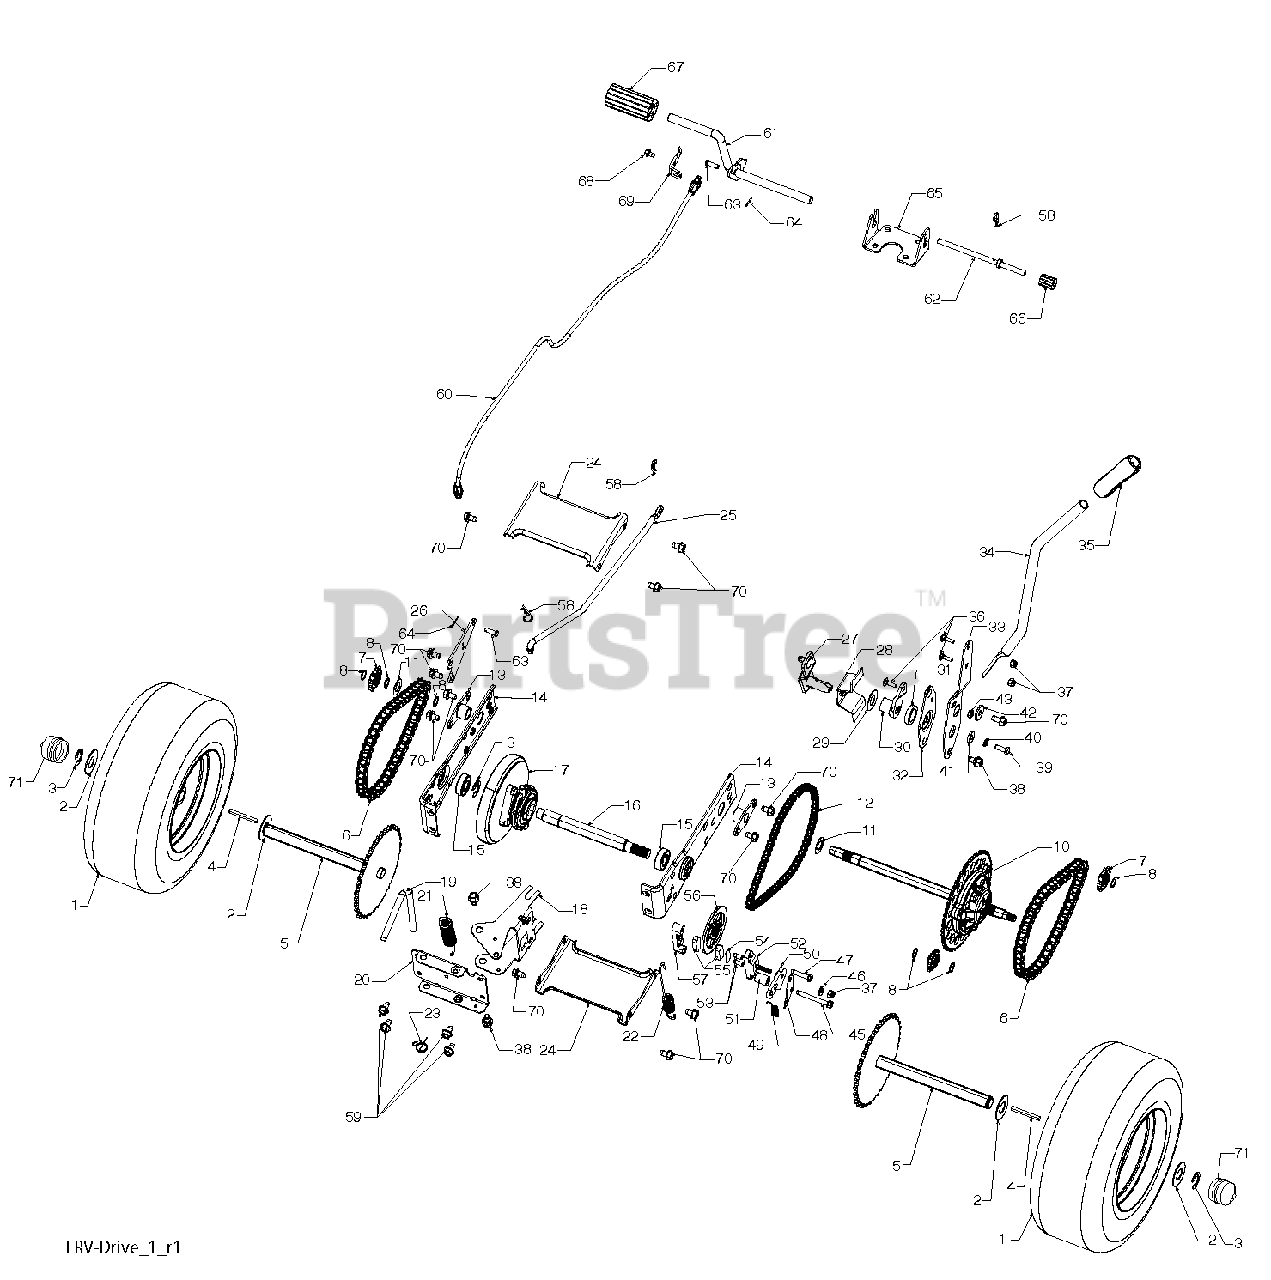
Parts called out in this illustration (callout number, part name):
1	WHEEL ASM (REAR)
2	WASHER, 16 GA.
3	E-CLIP
4	KEY. SQUARE
5	WELDMENT. DRIVE AXLE
6	CHAIN DRIVE
7	SPROCKET. 9 TOOTH SPLINED
8	RING, SNAP
10	DIFFERENTIAL ASM
11	WASHER, THRUST
12	CHAIN, PRIMARY DRIVE
13	BUSHING
14	BRACKET, CARRIER
15	BEARING ASM
16	SHAFT INPUT
17	WHEEL, FRICTION A5M
18	ARM, SHIFT
19	ROD, BYPASS
20	BRACE CARRIER REAR
21	SPRING, CARRIER
22	SPRING, BRAKE
23	SPRING, BYPASS
24	BRACE CARRIER BOX
25	LINK, SHIFT
26	ARM. CLUTCH
27	WELDMENT SHIFT LEVER
28	SUPPORT, SHIFT LEVER
29	WASHER, NYLON
30	HUB SHIFT LEVER
31	SPACER, NYLON
32	MNTG BRKT. SHIFT ARM
33	BRACKET, SHIFTER FLEX
34	TUBE SHIFT ARM
35	GRIP, HANDLE
36	BOLT, CARRIAGE - 114-20 X 3/4
37	NUT NYLON LOCK 114-20
38	BOLT, SHOULDER
39	BOLT, 1/4-20 X 3/4
40	WASHER, LOCK
41	WASHER FLAT
42	WASHER, SERRATED
43	NUT, CROWN LOCK 114-20
45	SCREW 1/4-20 X 2 114
46	WASHER
47	SCREW, 1/4-20 X 1 1/2
48	PLATE BRAKE ANTI - ROTATE
49	SPRING, BRAKE RETURN
50	ARM, BRAKE
51	SPACER RETURN
52	CALIPER, BRAKE ASM
53	PIN, DOWEL 1/4
54	PLATE, BRAKE PAD
55	PUCK BRAKE
56	ROTOR, BRAKE
57	CAP, BRAKE CALIPER
58	PIN, RETAINER
59	BOLT, 5/16-16 X 112
60	CABLE, BRAKE
61	WELDMENT, PEDAL
62	ROD, PARKING BRAKE
63	PIN, .25 X .75 CLEVIS
64	PIN, 1/16 DIA. COTTER
65	BRACKET, BRAKE SUPPORT
66	COVER PEDAL
67	COVER, BRAKE PEDAL
68	SCREW, 1/4-20 X 1/2
69	BRAKE CABLE MOUNT
70	BOLT, 5/16-18 X 3/4
71	CAP HUB AXLE
